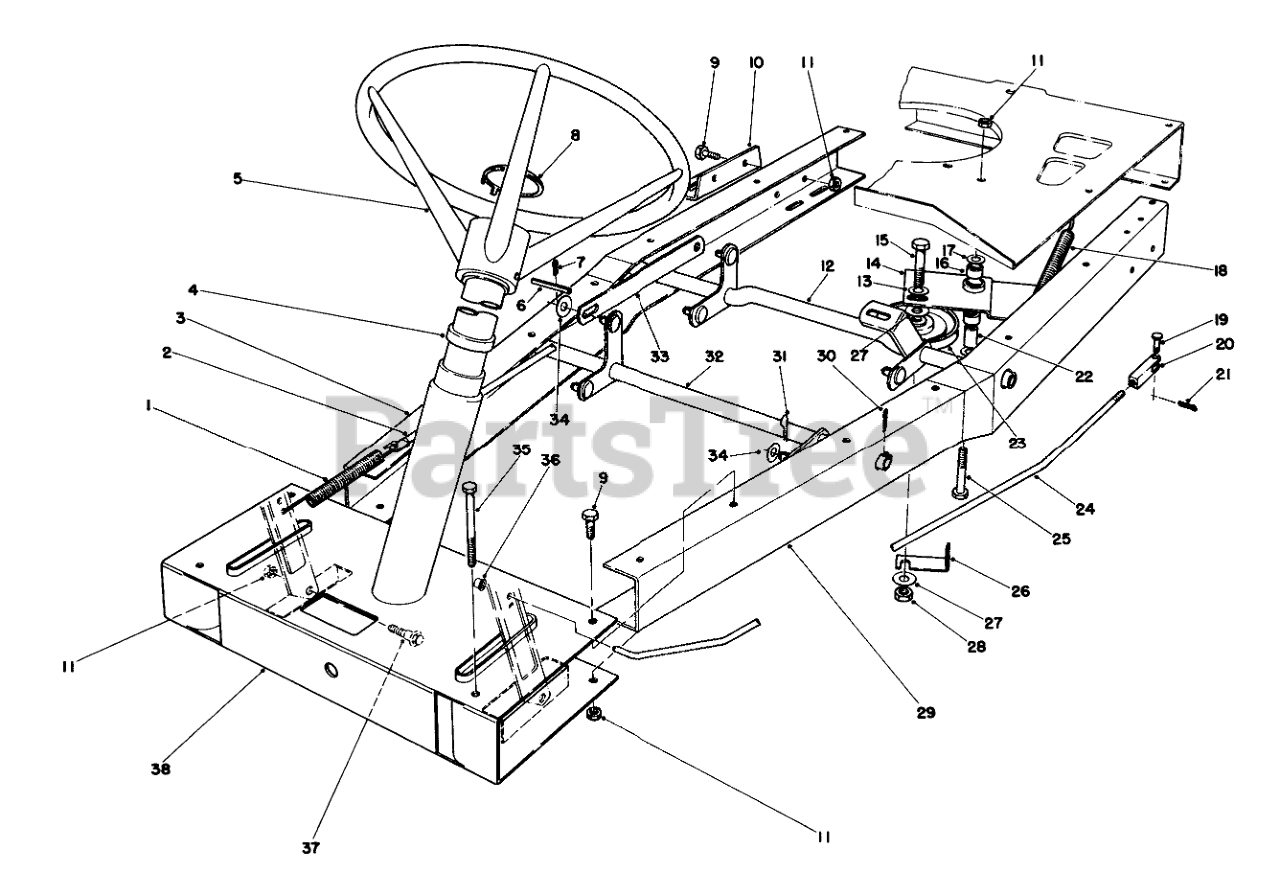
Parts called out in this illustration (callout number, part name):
1	BRAKE TENSION SPRG O
2	Brake Rod
3	Frame-Channel R.H.
4	STEERING TUBE WA BO
5	Steering Wheel
6	PIN-ROLL
7	PIN-COTTER
8	Insert-Steering Wheel
9	SCREW-HH
10	Mount-Axle Brg.
11	NUT-LOCK, CONE
12	REAR HT ADJ WA B
13	WASHER-FLAT
14	Traction Idler (Incl. Ref. #16)
15	SCREW-HH
16	BUSHING
17	WASHER-PLAIN
18	Clutch Tension Spring
19	PIN-CLEVIS
21	PIN-COTTER
22	PIVOT SPACER
23	PULLEY-IDLER
24	Clutch Rod
25	SCREW-HH
26	RETAINER-BELT
27	WASHER-FLAT
28	NUT-LOCK, SIDE
29	LH FRAME CHANNEL B
30	PIN-COTTER
31	PIN-COTTER
32	FRONT LIFT WA B
33	Linkage-Height Adj.
34	WASHER-FLAT
35	SCREW-HH
36	PUSH ON SPEED NUT 1/4
37	SCREW-SHOULDER
38	Front Frame
